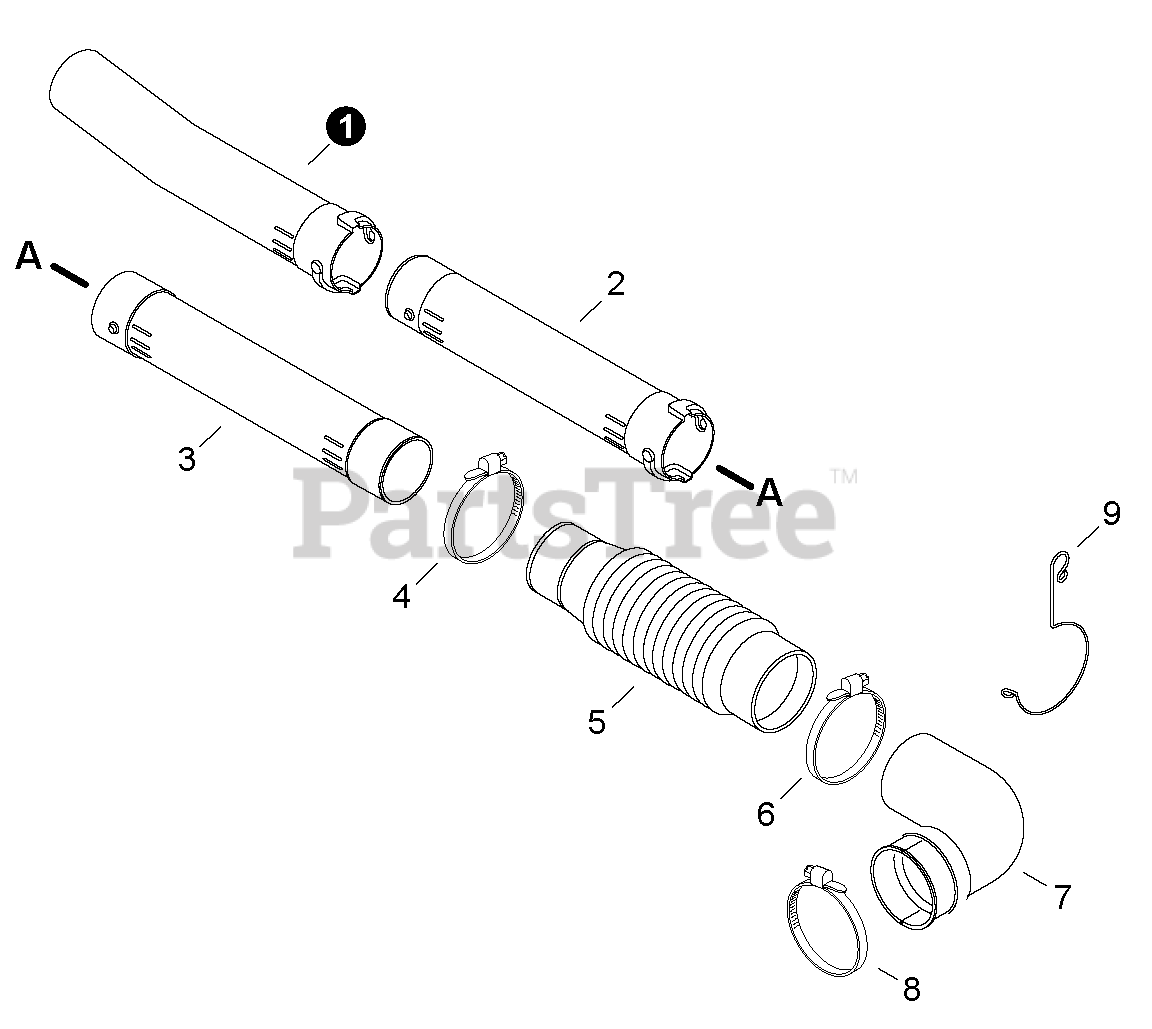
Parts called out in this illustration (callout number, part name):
1	TUBE, BLOWER - ROUND NOZZLE
2	TUBE, BLOWER - EXTENSION
3	TUBE, BLOWER - SWIVEL
4	CLAMP
5	TUBE, BLOWER - FLEXIBLE
6	CLAMP
7	TUBE, BLOWER - ELBOW
8	CLAMP
9	HOLDER, THROTTLE CABLE
